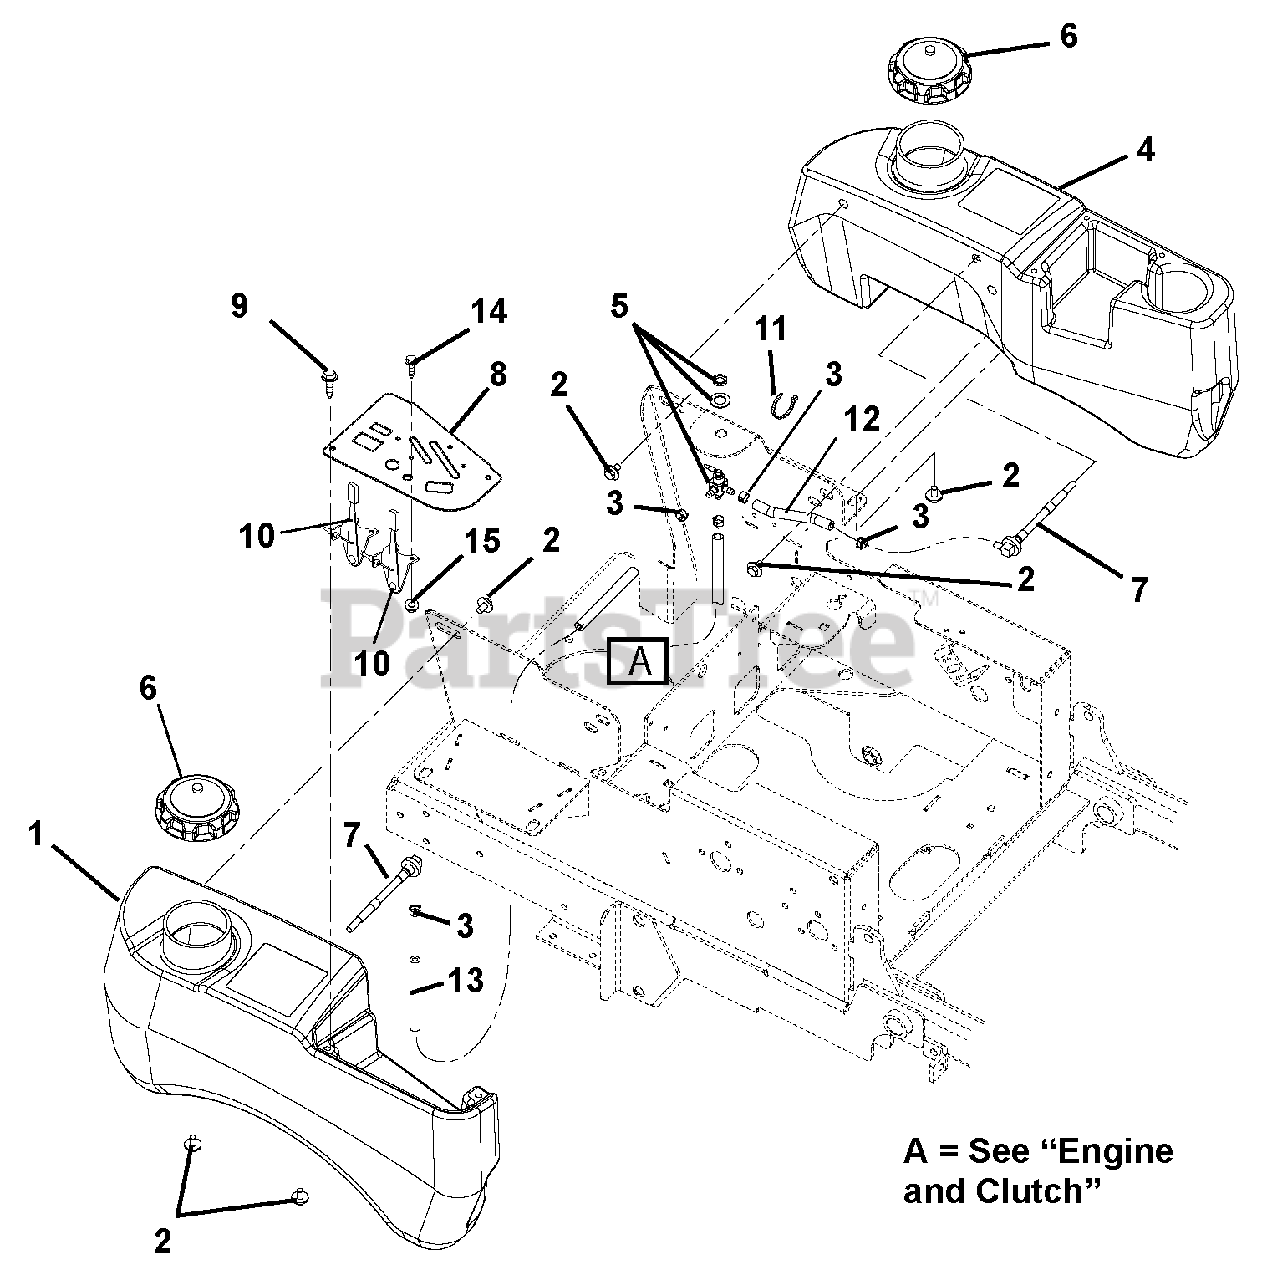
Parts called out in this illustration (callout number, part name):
1	Tank, Gas- Right Hand
2	Bolt, SEMS .31-18 x .62
3	Clamp, Fuel Line
4	Tank, Left Hand Fuel
5	Valve, Fuel
6	Cap, Fuel
7	Assembly, Small Tank Fuel Pick-up
8	Panel, Control
9	Screw, Machine 10-24 x .50
10	Cable, Control
11	Cable Tie
12	Hose, .25 Low-PERM Bulk Gas
13	Hose, .25 Low-PERM Bulk Gas
14	Screw, Machine 10-24 x .50 Hex Washer Head
15	Nut, Locking-Nylon 10-24 with Insert
